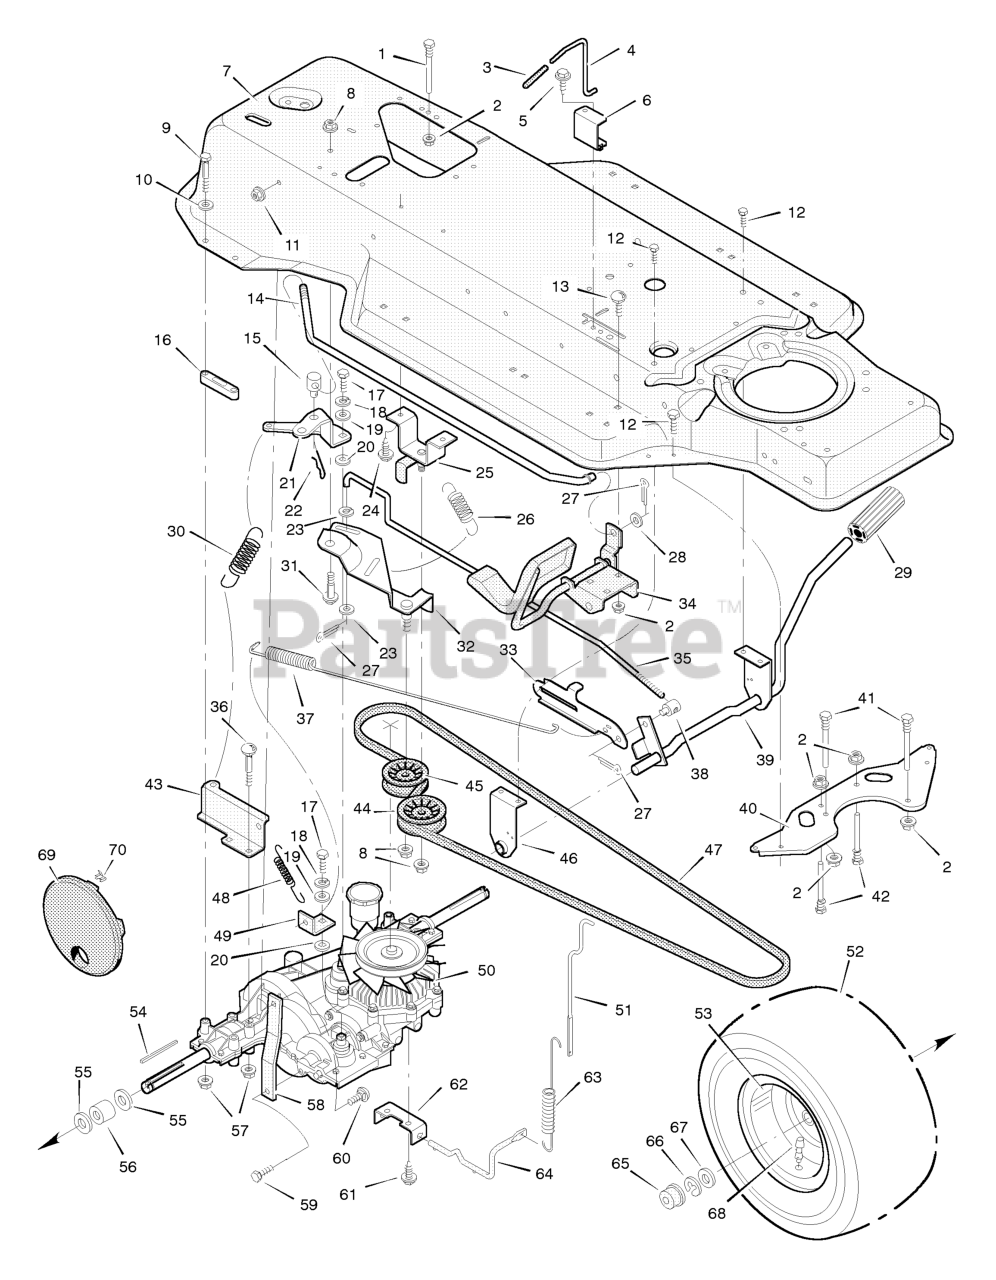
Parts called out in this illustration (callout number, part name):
1	Guide, Belt
2	Nut, Flange
4	Rod, Parking Brake
6	Bracket, Guide
7	Frame Assembly
8	Nut, Flange
10	Washer
11	Nut, Flange
13	Bolt, Carriage
14	Rod, Control
15	NUT, Adjusting, 1/2-13
16	Spacer, Hydro
18	Lockwasher
21	Lever, Control
22	Hair Pin
23	Washer
25	Idler Mount Assembly
26	Spring, Extension
27	Cotter Pin
29	Pedal
30	Spring, Extension
31	Shoulder Bolt
32	Idler Bracket Assembly
33	Latch, Parking Brake
34	Pedal Assembly
35	Clutch Rod
36	Carriage Bolt
37	Spring, Extension
38	Nut, Adjusting
39	Pedal Lever Assembly
40	Plate, Belt Guide
41	Screw, Guide
42	Screw, Guide
43	Bracket, Spring Mount
44	Idler Pulley
45	Idler Pulley
46	Support, Pedal
47	V- Belt
48	Spring, Extension
49	Lever, Brake
50	Transaxle **
51	Rod, Dump Valve
52	Wheel & Tire Assembly
53	Tire *
54	Square Key
56	Spacer, Wheel
57	Nut, Flange
58	Strap, Torque
60	Carriage Bolt
62	Bracket, Dump Valve
63	Spring, Extension
64	Rod, Dump Valve
65	Hub Cap
68	Valve Stem
69	Disc, Wheel
70	Clip, Retainer
